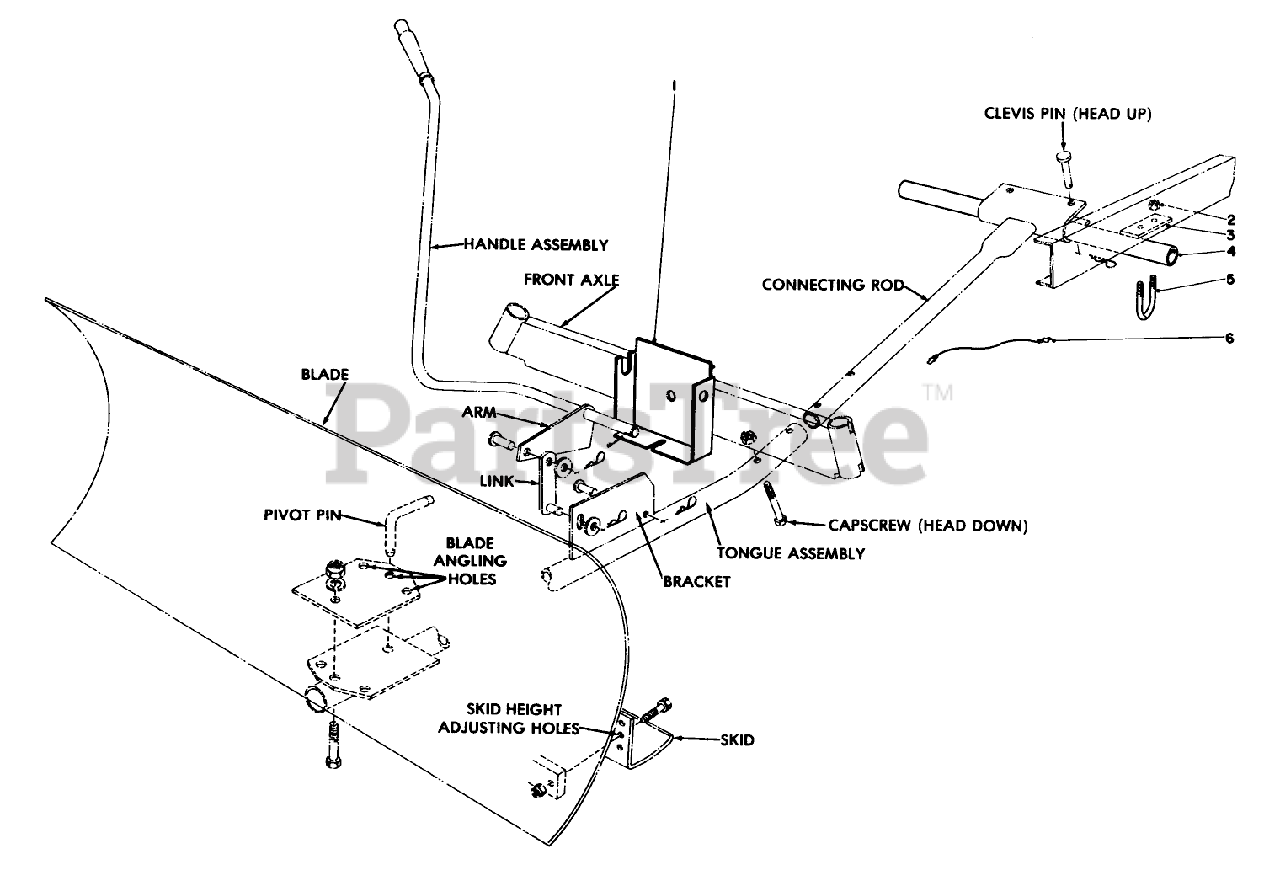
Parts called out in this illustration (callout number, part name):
1	Bracket
2	NUT-LOCK, CONE
3	Reinforcing Plate
4	Support Tube
5	U-Bolt
6	Jumper Wire
